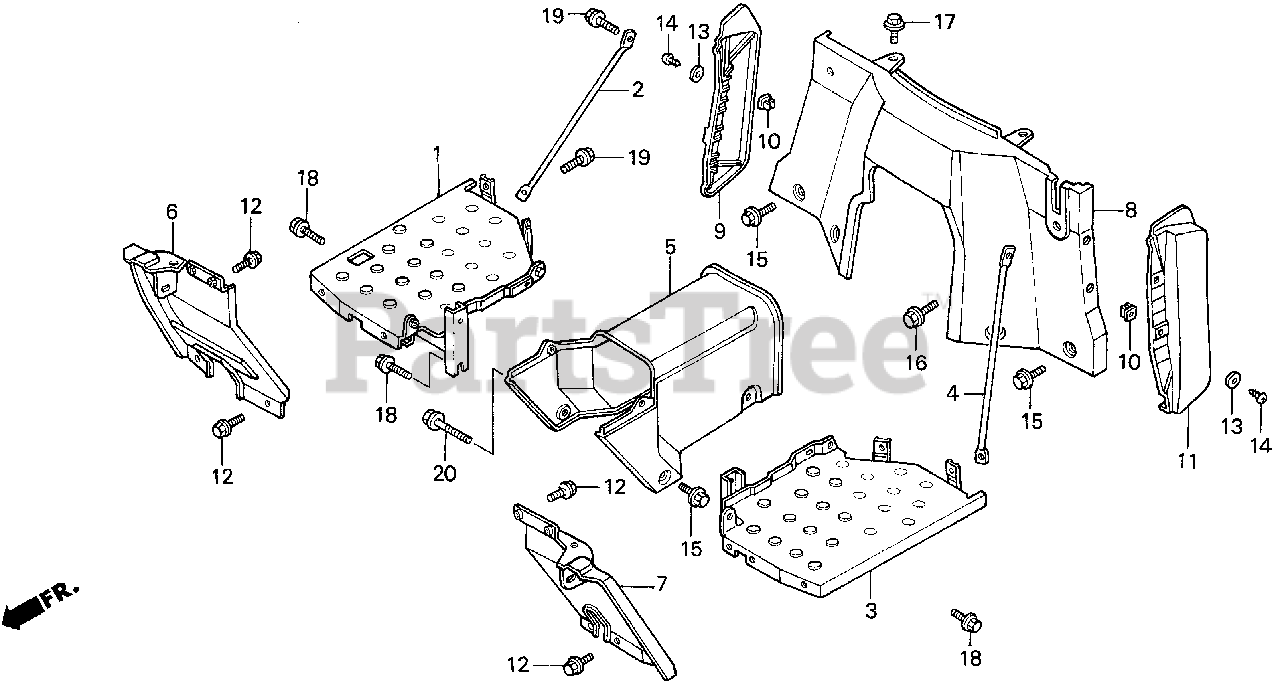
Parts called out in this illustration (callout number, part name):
1	STEP, R. *R165* (JOLLY RED)
2	ROD, R. STEP TENSION
3	STEP, L. *R165* (JOLLY RED)
4	ROD, L. STEP TENSION
5	FLOOR *R165* (JOLLY RED)
6	FENDER, R. FR. *R165* (JOLLY RED)
7	FENDER, L. FR. *R165* (JOLLY RED)
8	COVER, RR. *R165* (JOLLY RED)
9	COVER, R. SIDE *R165* (JOLLY RED)
10	NUT, NYLON (6MM)
11	COVER, L. SIDE *R165* (JOLLY RED)
12	BOLT, FENDER (6X18)
13	WASHER (6MM)
14	SCREW, TAPPING (6X20)
15	BOLT, FLANGE (6X12)
16	BOLT, FLANGE (6X12)
17	BOLT, FLANGE (6X12)
18	BOLT, FLANGE (8X14)
19	BOLT, FLANGE (8X16)
20	BOLT, FLANGE (6X20)
